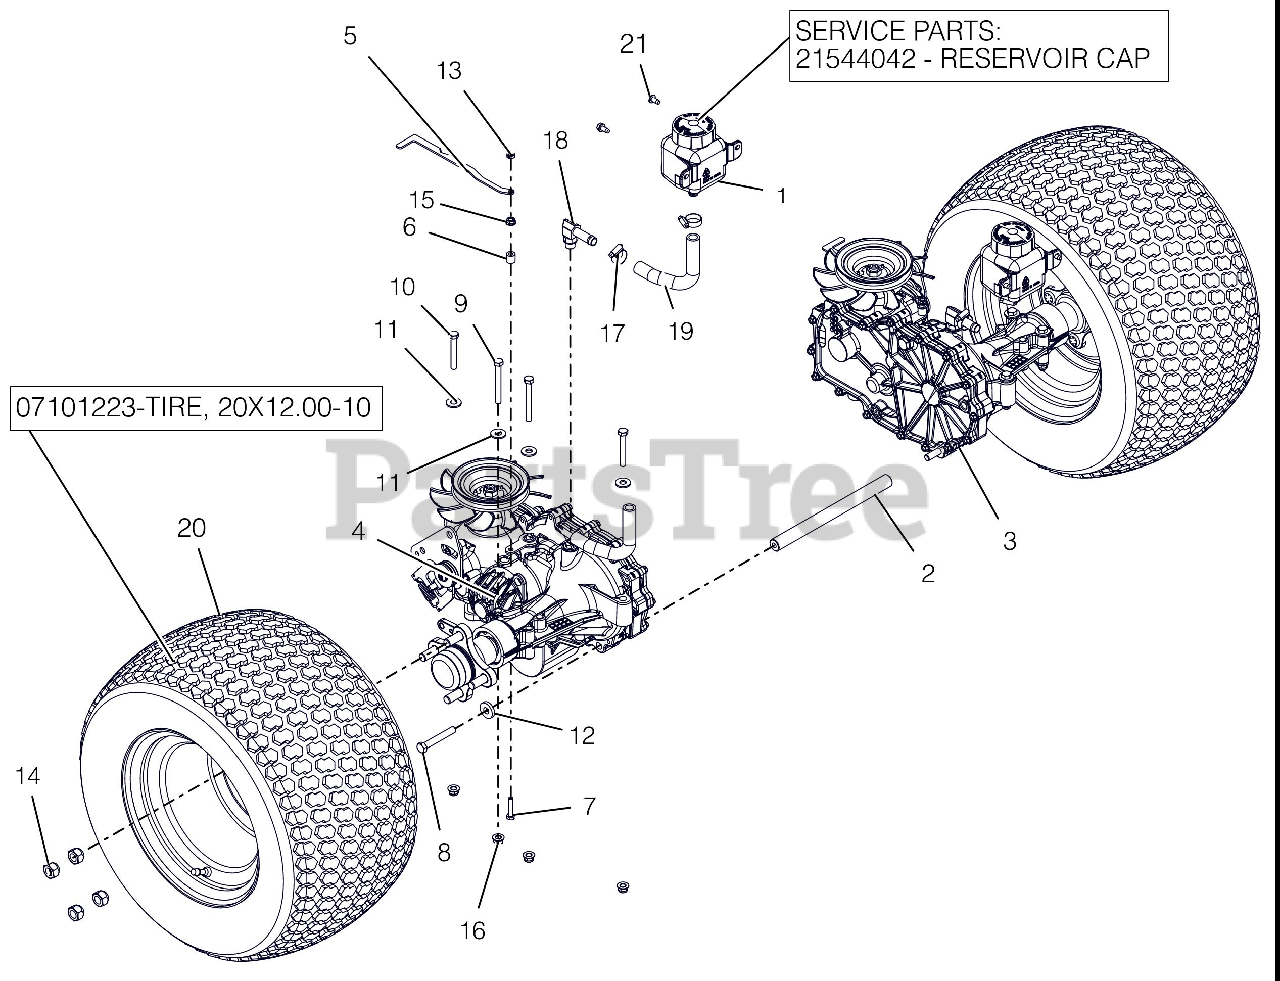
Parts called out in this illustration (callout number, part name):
1	TANK, EXPANSION
1	CAP, HYDRO RESERVOIR REPLAC.
2	ROD, TRANSAXLE BRACE (LONG)
3	TRANSAXLE,ZT2800 LH
4	TRANSAXLE,ZT2800 RH
5	BRKT, DUMP VALVE
6	BSHG-SLV .265X.500X.500
7	@BLT-HEX .25-20X1.25 GR5 YWZC
8	@BLT-HEX .38-16X2.50 GR5 YWZC
9	@BLT-HEX .31-18X2.75 GR5 YWZC
10	@BLT-HEX .31-18X2.25 GR5 YWZC
11	@WSHR-FL-STL.38X.875X.083 YWZC
12	WSHR-FL-STL .406X1.00X.188 YWZ
13	NUT-LK-CTR JAM .25-20 YWZC
14	WHEEL NUT .500-20 YZ
15	@NUT-SPNLK-FLG .25-20 YWZC
16	@NUT-LK-NYL-FLG .31-18 YWZC
17	CLAMP,.88 DIA. HOSE
18	FITTING, HYD (90 DEG)
19	HOSE, FORMED LH XL
20	ASM, WHL/TIRE 20X8.00-10
20	TIRE, 20X12.00-10 (OTR)
21	SCR-TAP .25-20X.50 HWH TR YWZ
